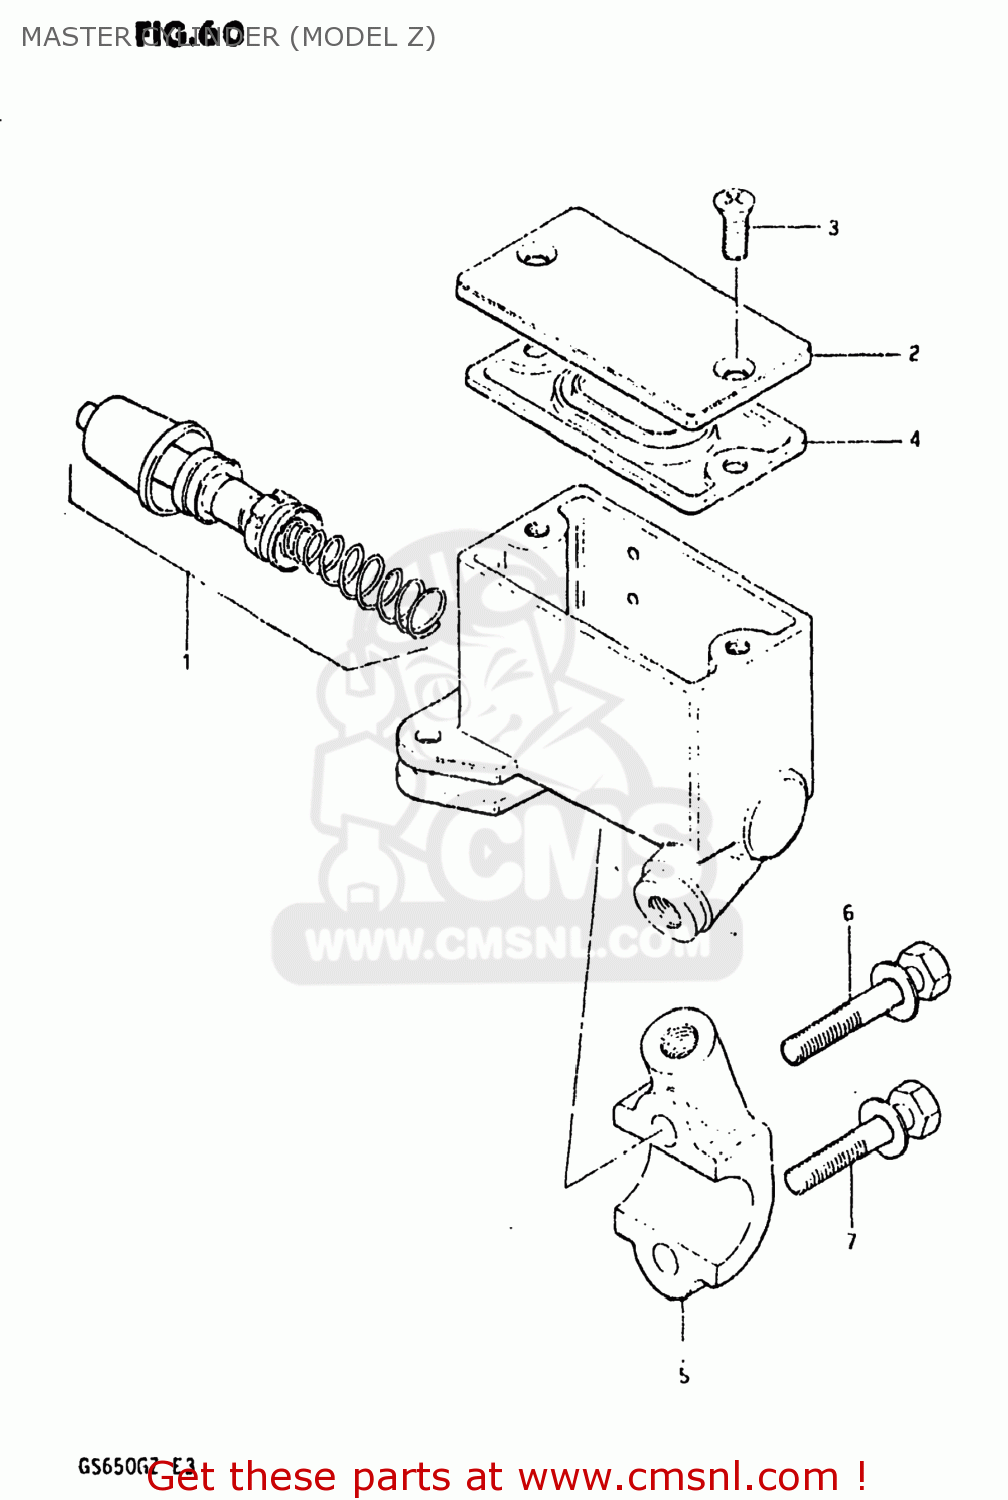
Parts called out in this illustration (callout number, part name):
1	PISTON & CUP SET
2	CAP,MASTER CYLINDER,REAR
3	SCREW,RESERVOIR CAP
4	DIAPHRAGM,MASTER CYLINDER
5	HOLDER
6	BOLT,MASTER CYLINDER H
7	BOLT,MASTER CYLINDER H
